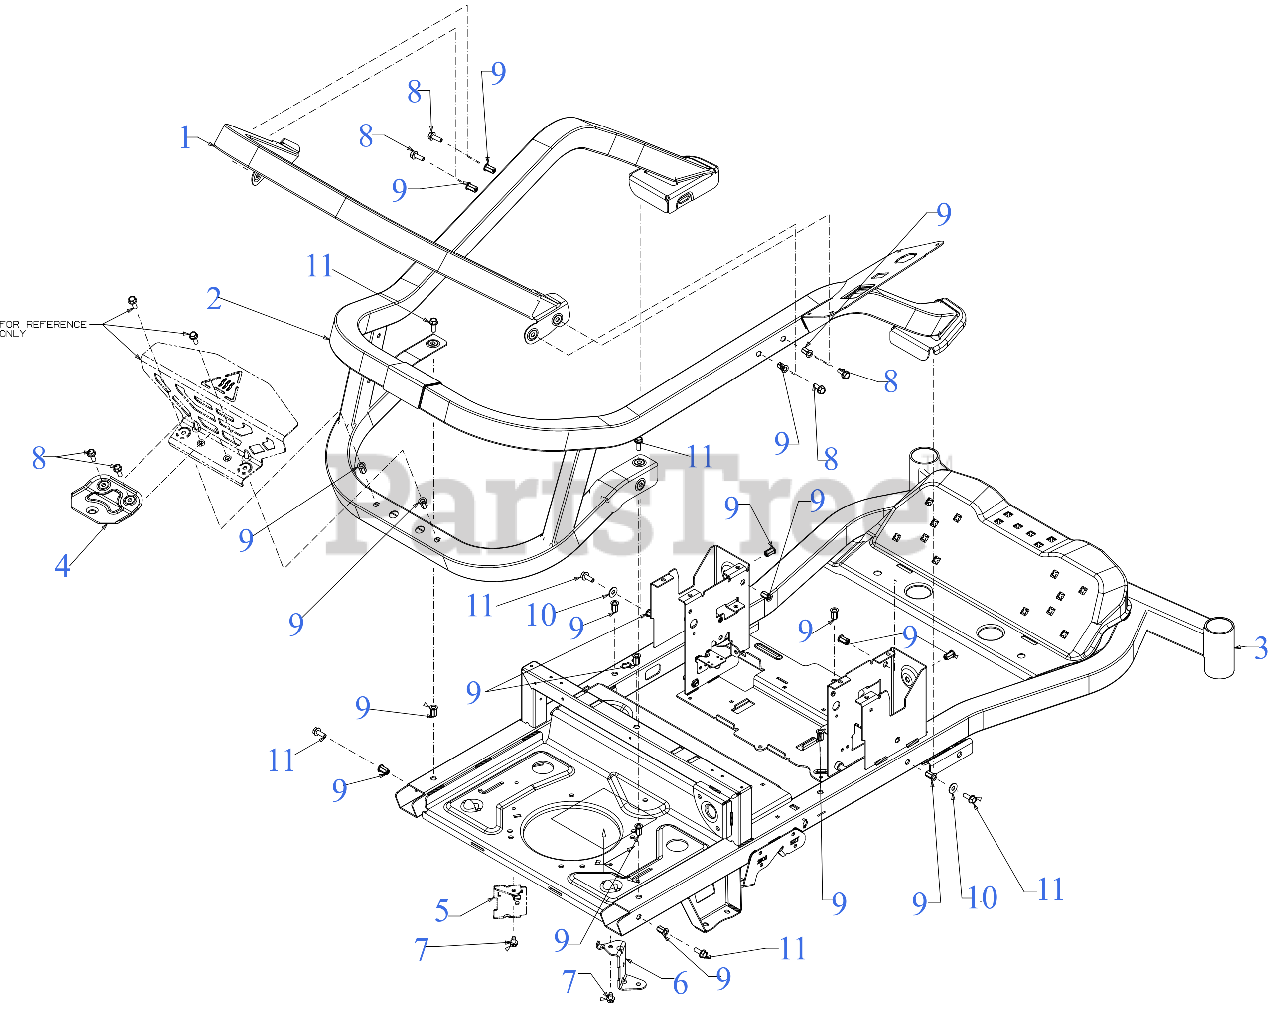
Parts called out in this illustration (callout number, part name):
1	UPPER FRAME HOOP
2	UPPER FRAME
3	FRAME
4	HITCH PLATE
5	TRANSMISSON MOUNT SUPPORT (LH)
6	TRANSMISSON MOUNT SUPPORT (RH)
7	SCREW 5/16-18 x .500
8	SCREW 5/16-18 x .875 GR5
9	NUT RIVET 5/16-18 LOCK
10	FLAT WASHER
11	SCREW 5/16-18 x 1.25
